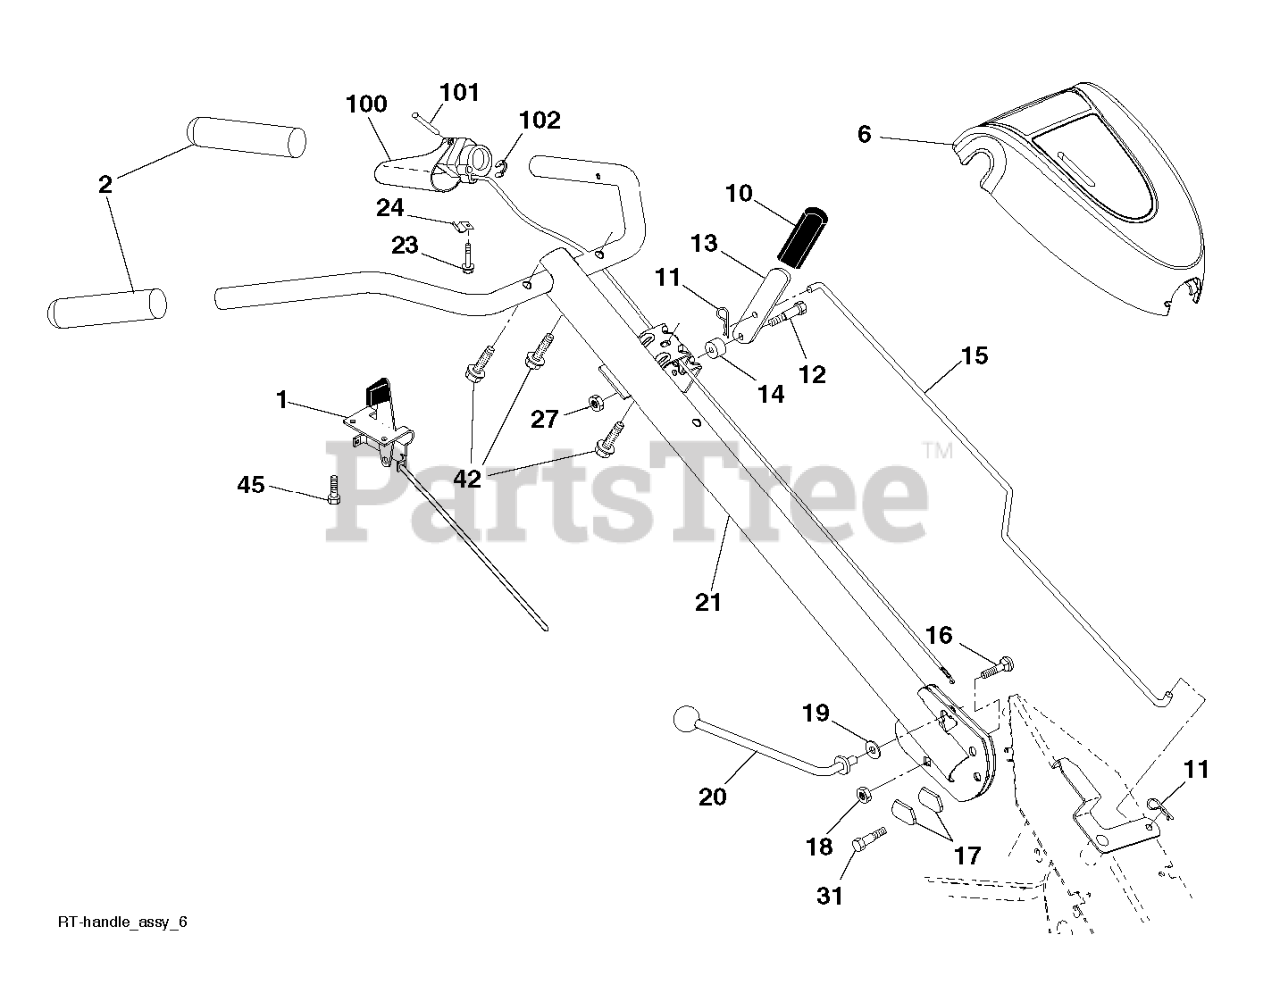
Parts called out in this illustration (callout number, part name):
1	CABLE ASSY THROTTLE
2	GRIP.1X5.06
6	CONSOLE HUSQVARNA W/THROTTLE T
10	GRIP HANDLE TILLER RED
11	RETAINER M
12	SHOULDER BOLT ST
13	HANDLE
14	GROMMET.RUBBER.CRT.TILLER
15	ROD SHIFT RT UNIVERSAL
16	BOLT D
17	LOCK.HANDLE.CRT
19	WASHER CRT
20	LEVER.LOCK.CRT
21	HANDLE.ASM.HUSQ/P.PRO.GREY
23	TAPPING SCREW
24	CLIP.PLATED
27	NUT T
31	BOLT.PIVOT
42	SCREW.#10 X 0.750.BOS
45	SCREW.#10 X 0.500
100	CONTROL.ASSEMBLY.TINE.TILLER
101	PIN, PIVOT
102	RETAINING.RING.#5103-25
